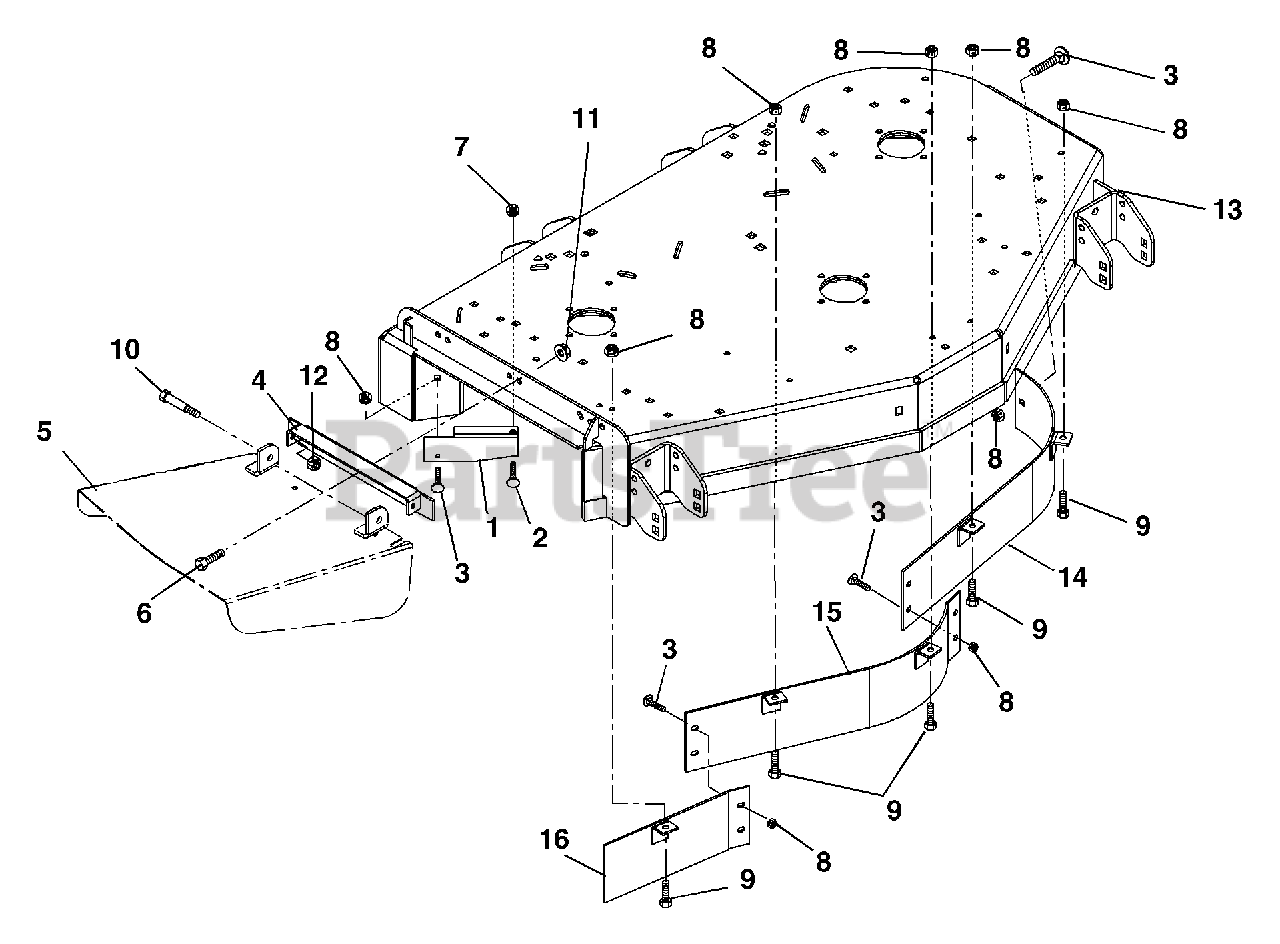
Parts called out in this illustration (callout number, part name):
1	DEFLECTOR, 60" (BLACK)
2	@BLT-RDHDSQNK .38-16X.75 G5YZ
3	@BLT-RDHDSQNK .31-18X.75 G5YZ
4	WLDMT. DISCH. CHUTE BRKT (RED)
5	WMT, DISCHARGE CHUTE 60"
6	@BLT-HEX .38-16X1.00 GR5 YWZC
7	@NUT-LK-TOP-FLG .38-16 YWZC
8	@NUT-LK-TOP-FLG .31-18 YWZC
9	@BLT-HEX .31-18X.75 GR5 YWZC
10	BLT-SHLDR .38-16X.38 SKH
11	@NUT-SPNLK-FLG .375-16 YWZC
12	@NUT-LK-CTR .38-16 YWZC
13	60" 7 GA MOWER DECK - RED
14	BAFFLE - LEFT FRONT - 60"
15	BAFFLE - CENTER FRONT - 60"
16	BAFFLE - RIGHT FRONT - 60"
